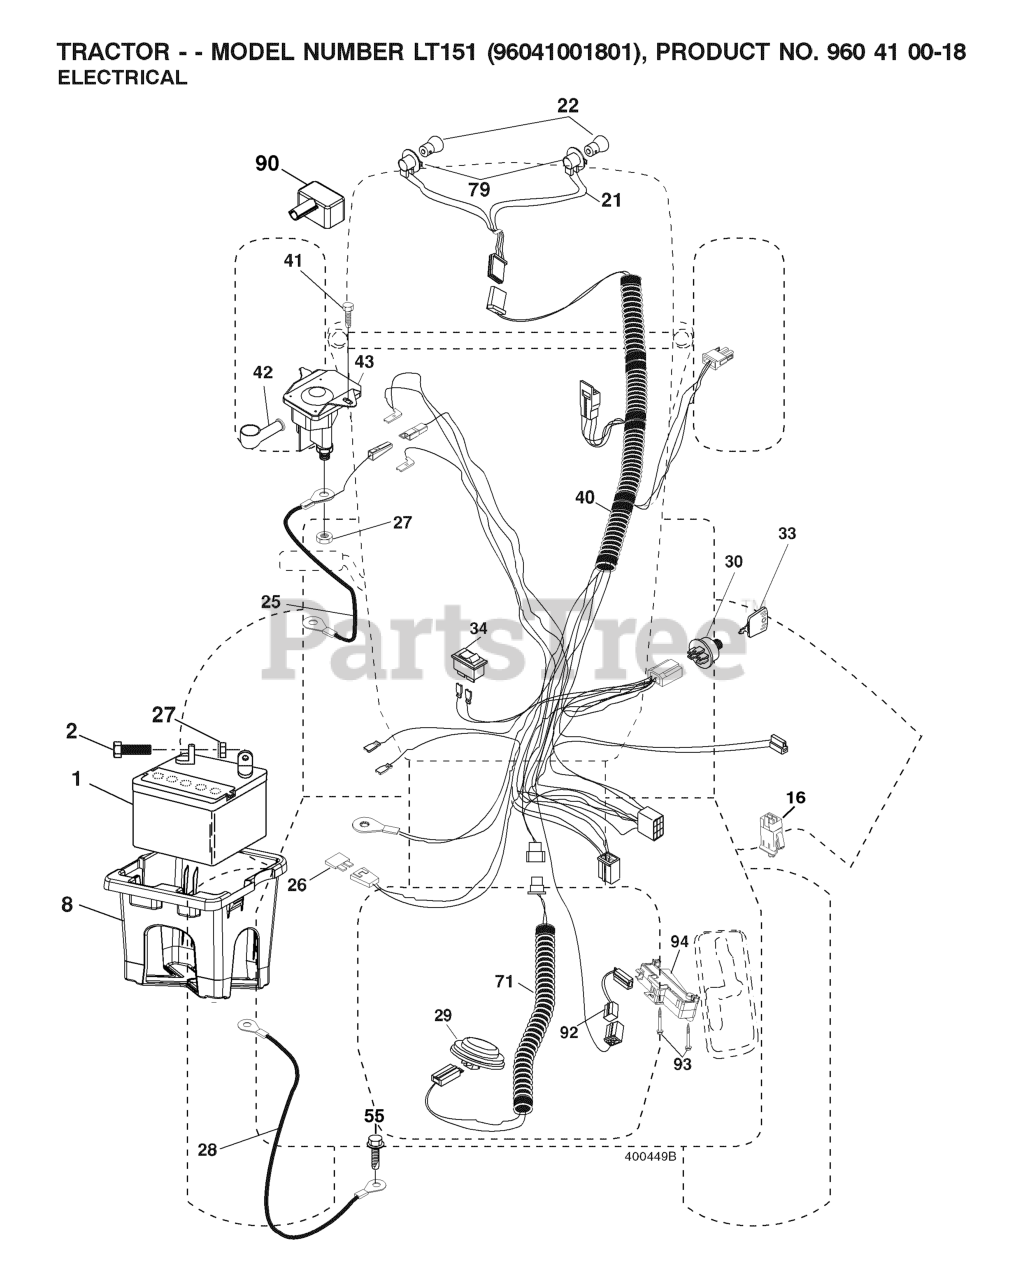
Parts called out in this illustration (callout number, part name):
1	BATTERY 12V .35 AMP
2	BOLT.HEX.1/4.X.3/4.DICHROMATE
8	BOX.BATTERY.MNT.REAR.L
16	SWITCH INTERLOOK PUSH-IN
21	HARNESS.LIGHT W/4152J BULBS
25	CABLE.STARTER.6GA.RED.
26	FUSE 20AMP
27	NUT
28	CABLE.BLACK.18"REAR.BA
29	SWITCH.SEAT.DELTA.OPC.
30	SWITCH.IGN.DELTA.W.LGH.ROS
33	KEY MLD GEN DELTA
40	HARNESS IGN. DASH
41	SCREW
42	TERMINAL COVER
43	SOLENOID.W/BRASS.PLUNGER
55	SCREW 5/16"
71	HARNESS.IGN.CHASS.TEX.REAR.BAT
79	BULB HOLDER ASM.
90	COVER, TERMINAL BATTERY
92	HARNESS.PIGTAIL.CONSLE
93	SCREW.PLASTITE
94	MODULE.REVERSE.ROS
